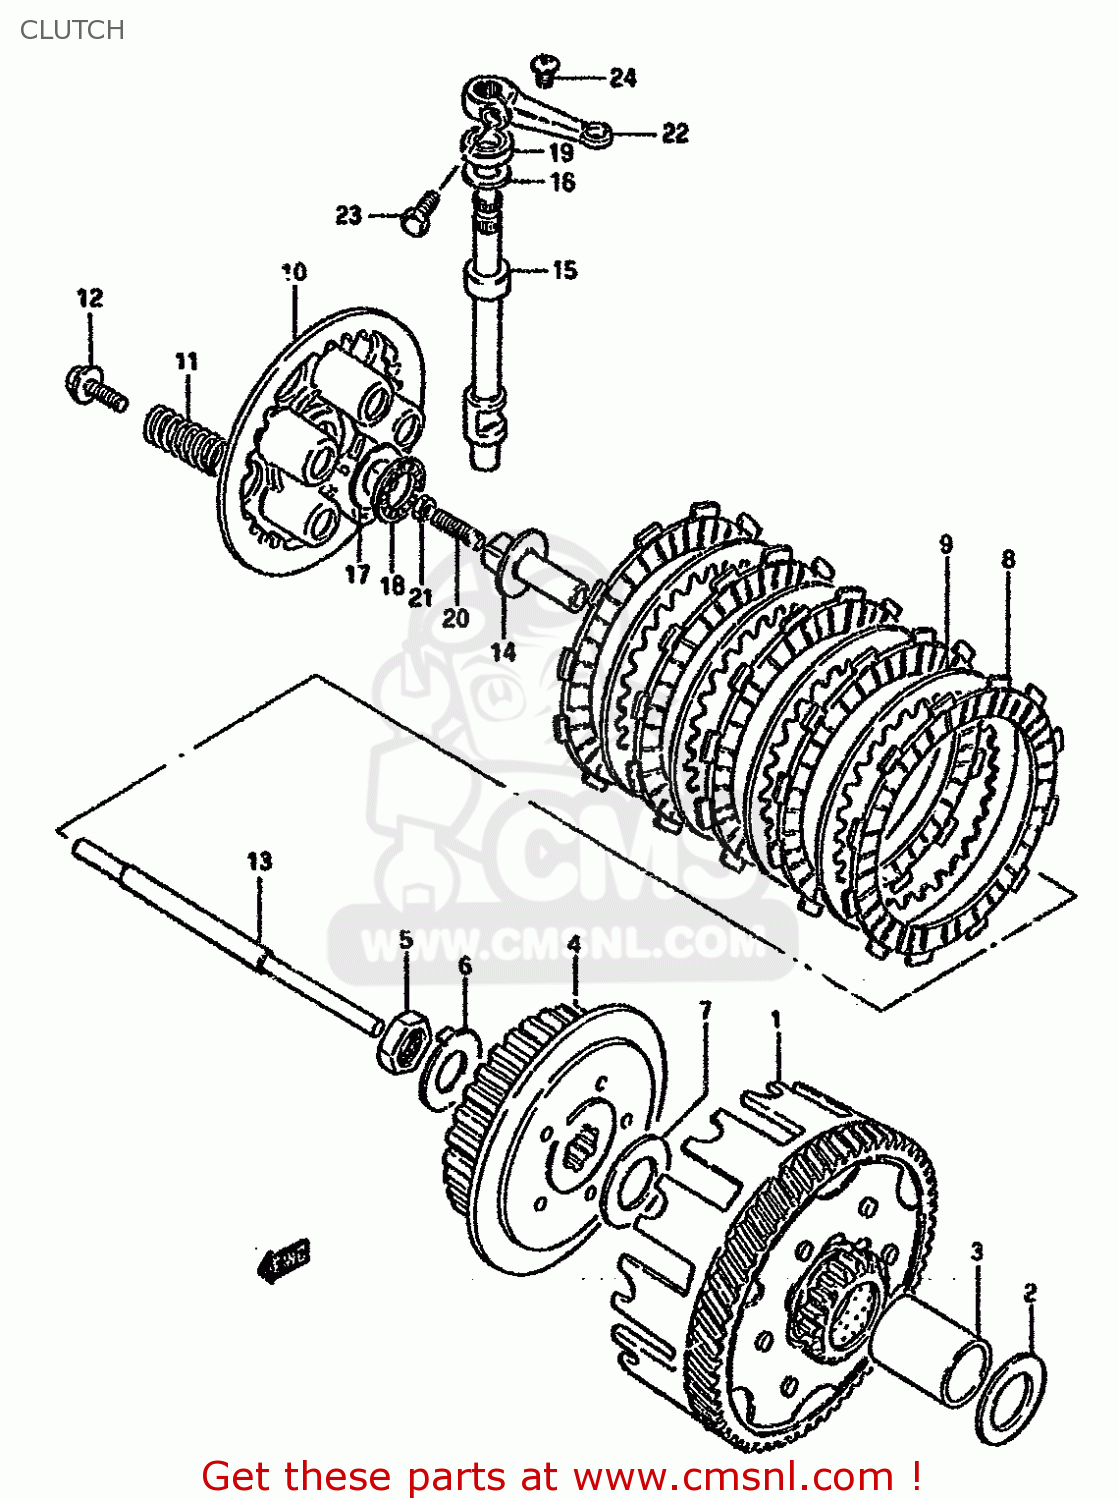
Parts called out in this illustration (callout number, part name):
1	GEAR ASSEMBLY,PRIMARY DRIVE
2	WASHER
3	SPACER
4	HUB,CLUTCH SLEEVE
5	NUT
6	WASHER
7	WASHER
8	PLATE,CLUTCH DRIVE(T:3.0) (NAS)
9	PLATE,CLUTCH DRIVEN (NAS)
10	PLATE,CLUTCH PRESSURE
11	SPRING
12	BOLT 5X16
13	ROD,CLUTCH PUSH
14	PIECE,CLUTCH PUSH
15	CAMSHAFT,CLUTCH RELEASE
16	WASHER,THRUST
17	WASHER
18	BEARING(15X28X2)
19	SEAL,OIL(10X20X6)
20	SCREW(6X25)
21	NUT
22	ARM,CLUTCH RELEASE
23	BOLT
24	SCREW
